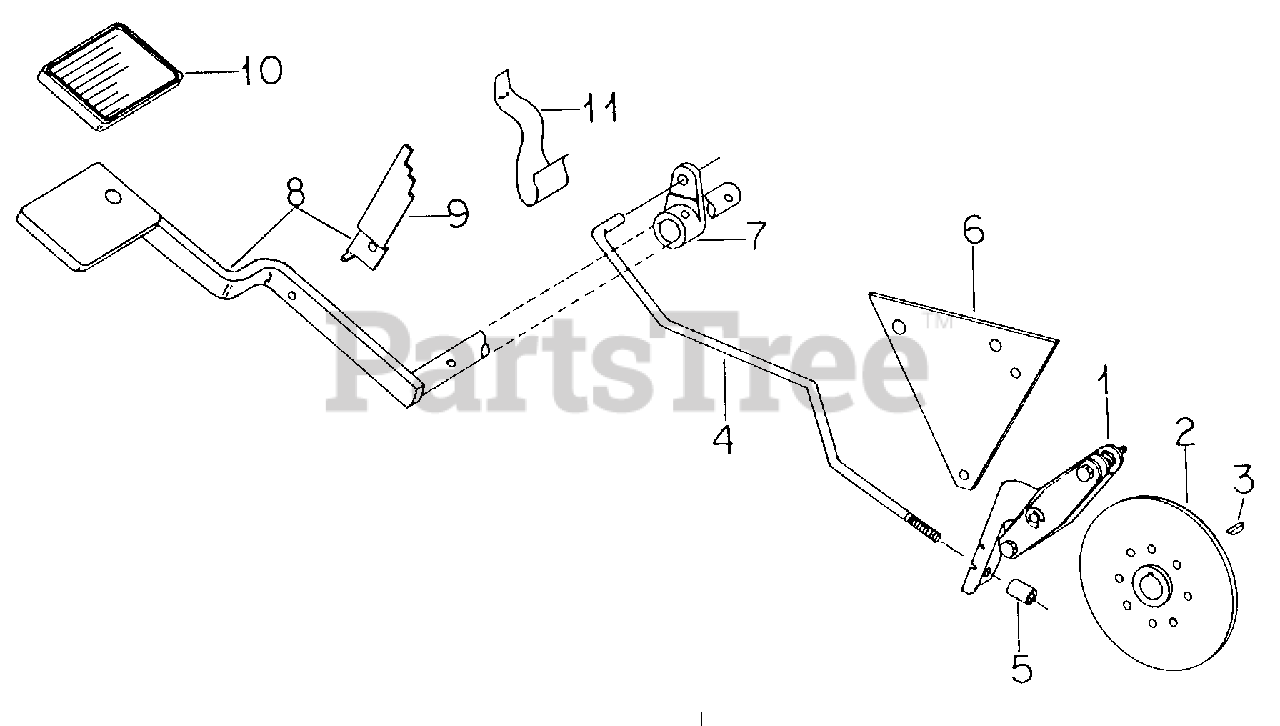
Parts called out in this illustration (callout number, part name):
1	Brake Assy, Caliper
2	Disc & Hub
3	Key, 3/16 X 3/4 Woodruff 9
4	Rod, Brake
5	Spacer, .493 X .675 X 1.00 Pipe
6	Support, Plate Brake (Spacer)
7	Lever, Brake Rod
8	Pedal Assy, Clutch
10	Pad, Pedal
11	Spring, Switch Operating
